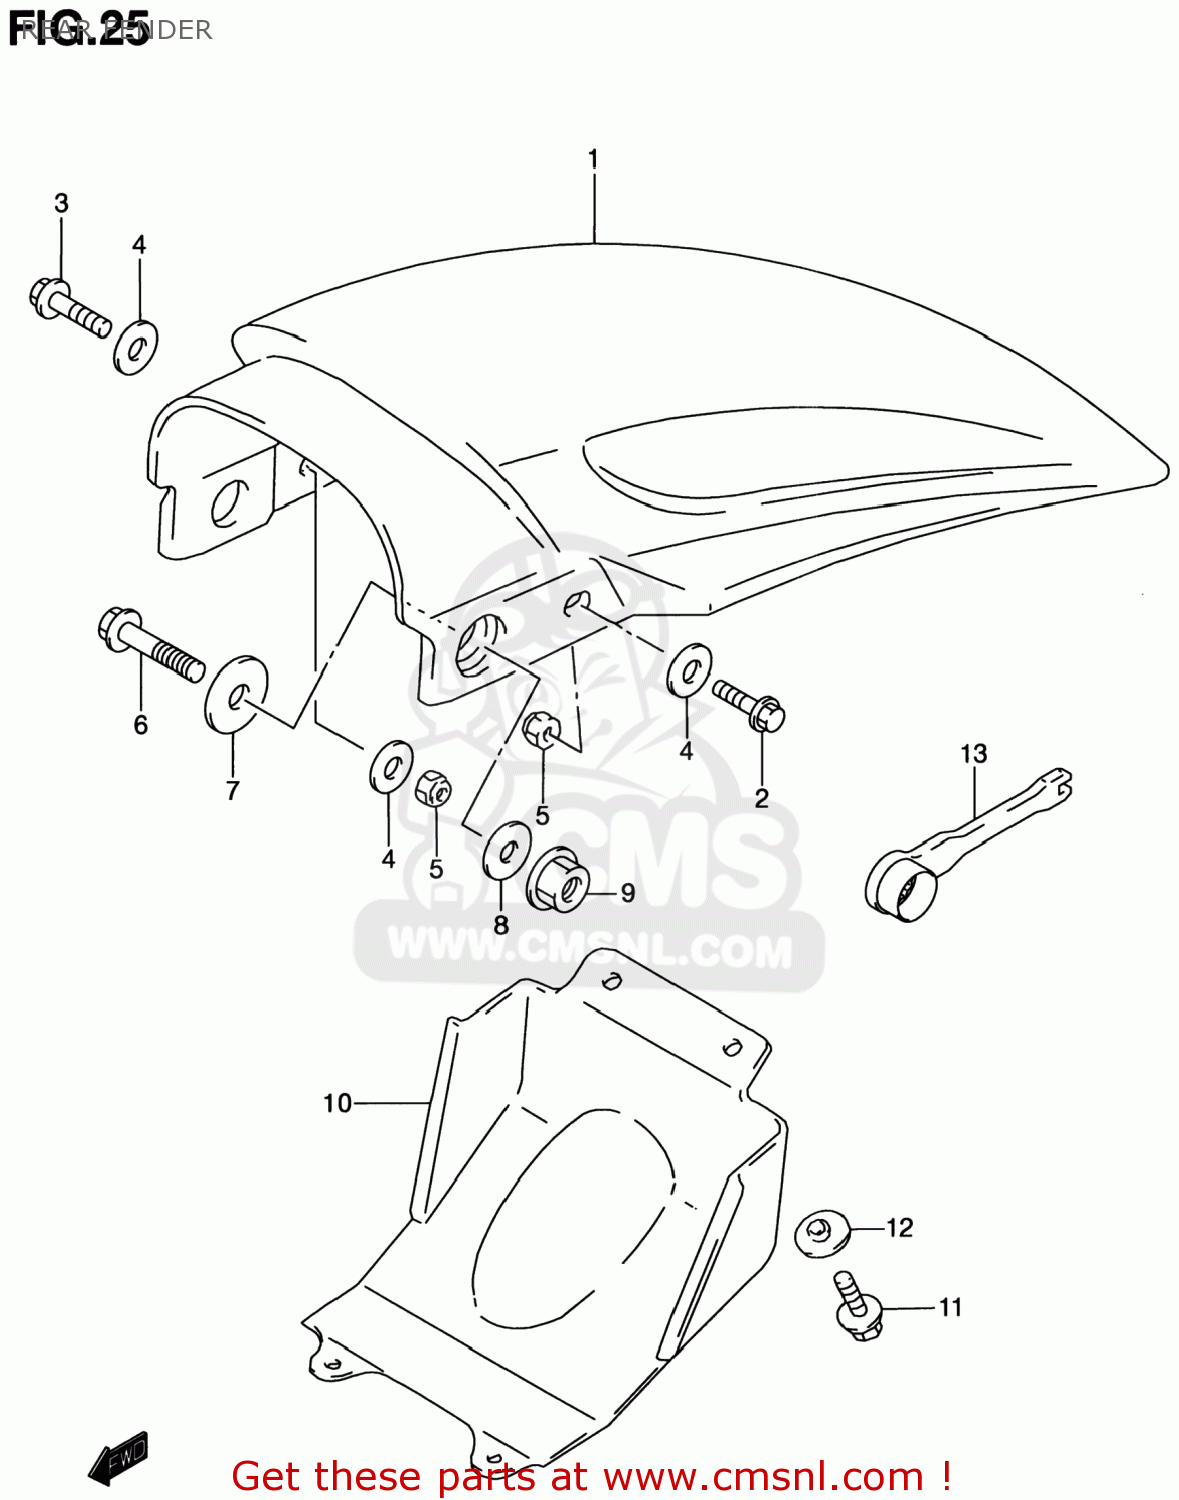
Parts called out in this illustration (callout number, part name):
1	FENDER,RR
2	SCREW
3	BOLT,G/S SWITC
4	WASHER(6.5X20X1.2)
5	NUT 6MM
6	BOLT,G/S SWITC
7	WASHER(6.5X26X2.3)
8	WASHER(6.5X18X1.6)
9	NUT
10	MUDGUARD,RR FENDER FR
11	BOLT
12	WASHER
13	SPARK PLUG WRENCH 21 & SPANNER 5.1
